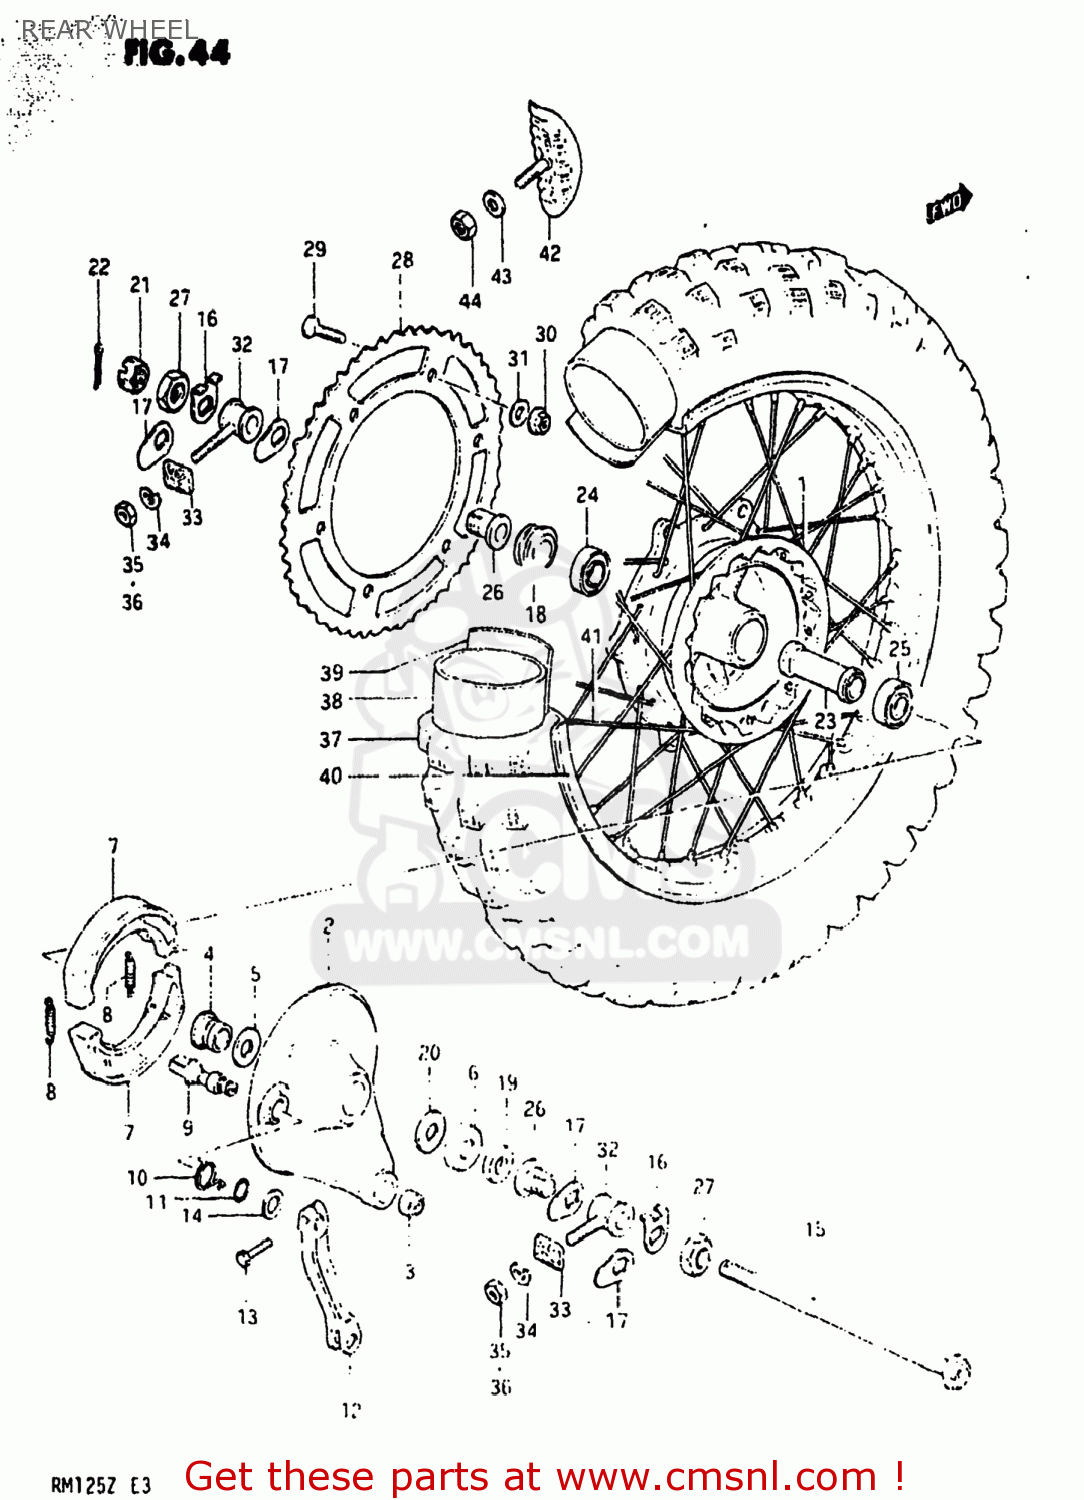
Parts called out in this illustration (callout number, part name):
1	DRUM,REAR HUB
2	PANEL SET,REAR HUB
3	SPHERICAL BRNG,TORQUE LINK
4	SPACER,RR BRAKE ANCHOR PANEL
5	SEAL,OIL(20X27X5)
6	CVR,RR BRAKE AHR PNL DUST SEAL
7	SHOE,BRAKE (MCA)
8	SPRING(L:34)
9	CAM,FR BRAKE
10	SPRING
11	O RING(D:2.5,ID:11.4)
12	LEVER,RR BRAKE CAM
13	BOLT
14	WASHER(12.5X20X1)
15	AXLE,REAR
16	WASHER,CHAIN ADJUSTER
17	WASHER,CHAIN ADJUST GUIDE
18	SPACER,RR AXLE,L
19	SPACER,REAR AXLE,RIGHT
20	WASHER,THRUST
21	NUT
22	COTTER PIN
23	SPACER
24	BEARING
25	BEARING
26	SPACER,CHAIN ADJUSTER
27	NUT
28	SPROCKET,RR(NT:51 AL)
29	SCREW(8X33.5)
30	NUT
31	WASHER
32	ADJUSTER,CHAIN
33	PLATE,CHAIN ADJUSTER GUIDE,R
34	LOCK WASHER
35	NUT
36	NUT
37	TIRE
38	TUBE ASSEMBLY,WHEEL,INNER
39	PROTECTOR,INNER TUBE
40	RIM,REAR WHEEL
41	SPOKE SET,REAR WHEEL
42	STOPPER,BEAD
43	WASHER
44	NUT
